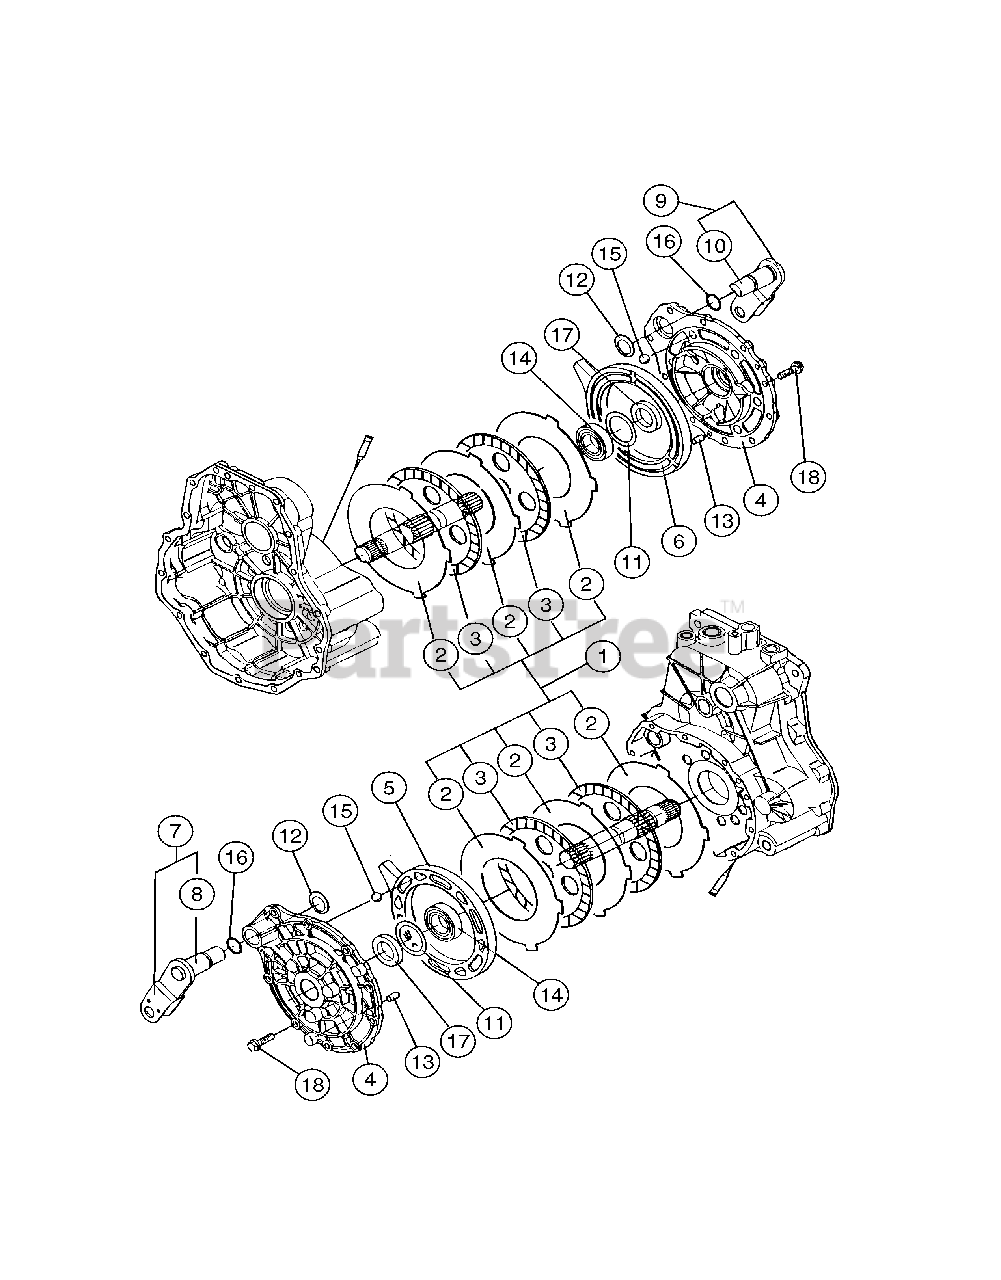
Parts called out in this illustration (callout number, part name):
2	Steel Plate
3	Friction Plate, 175
7	Cam Lever, Complete, LH
8	Cam Lever Shaft
9	Cam Lever, Complete, RH
10	Cam Lever Shaft
11	Washer, 42 x 54.6 x 1
14	Bearing, 6006
16	Packing, P 21
17	Seal, TC304708
18	Tapping Screw, 8 x 30
18	Flange Bolt, M8 x 30
